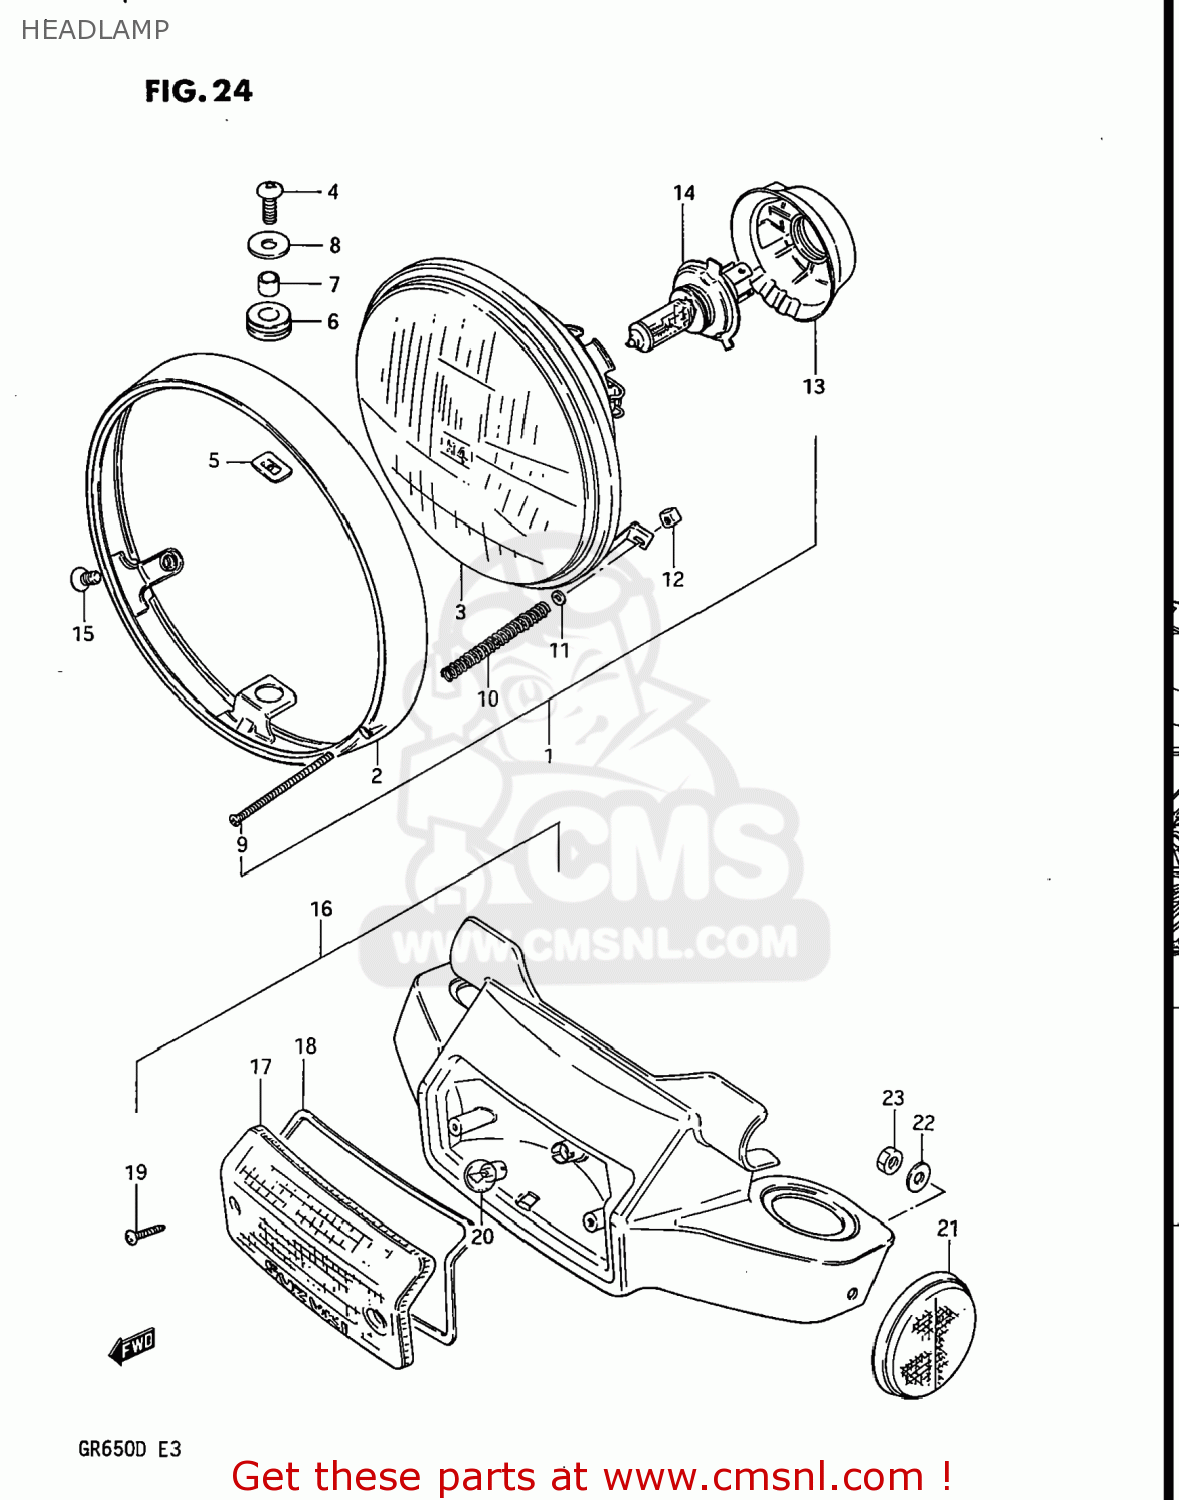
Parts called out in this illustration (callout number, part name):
1	LAMP ASSEMBLY,HEAD
2	RIM,HEAD LAMP
3	LAMP UNIT
4	SCREW(5X14)
5	NUT
6	CUSHION
7	SPACER
8	WASHER
9	SCREW,HEADLAMP ADJUST
10	SPRING,HEADLAMP ADJUST
11	WASHER
12	NUT
13	COVER,SOCKET
14	BULB(12V60/55W,H4)
15	SCREW(5X12)
16	LAMP ASSEMBLY,FRONT POSITION
17	LENS
18	GASKET,POSITION LAMP
19	SCREW,POSITION LENS
20	BULB
21	REFLEX REFLECTOR,RR
22	WASHER
23	NUT
